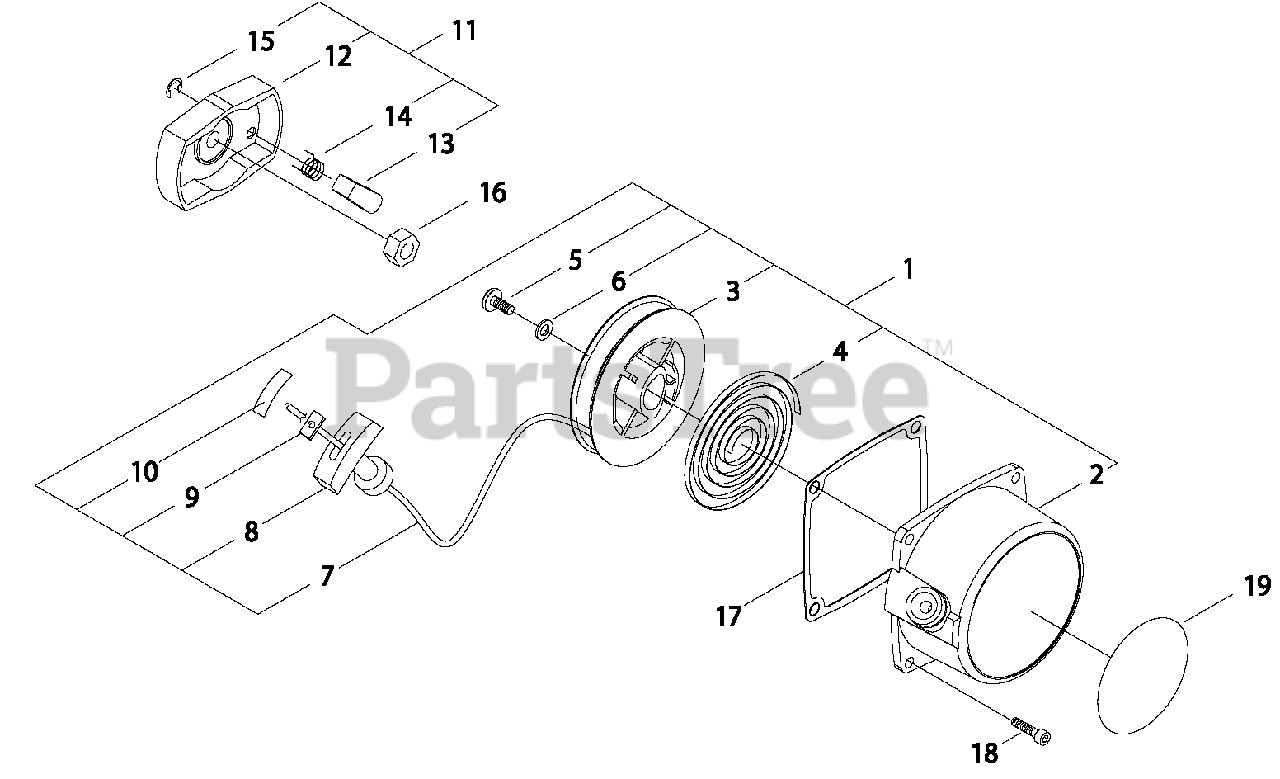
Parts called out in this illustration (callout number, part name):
1	STARTER ASSY
2	CASE, RECOIL STARTER
3	REEL, ROPE
4	SPRING, RECOIL
5	SCREW 5
6	WASHER
7	ROPE, STARTER
8	GRIP, STARTER
9	RETAINER, ROPE
10	TAPE
11	PULLEY ASSY, STARTER
12	PULLEY, STARTER
13	PAWL, STARTER
14	SPRING, RETURN
15	E-RING 4
16	NUT M8×H5
17	GASKET, RECOIL STARTER
18	BOLT M4×16
19	LABEL, TRADE
